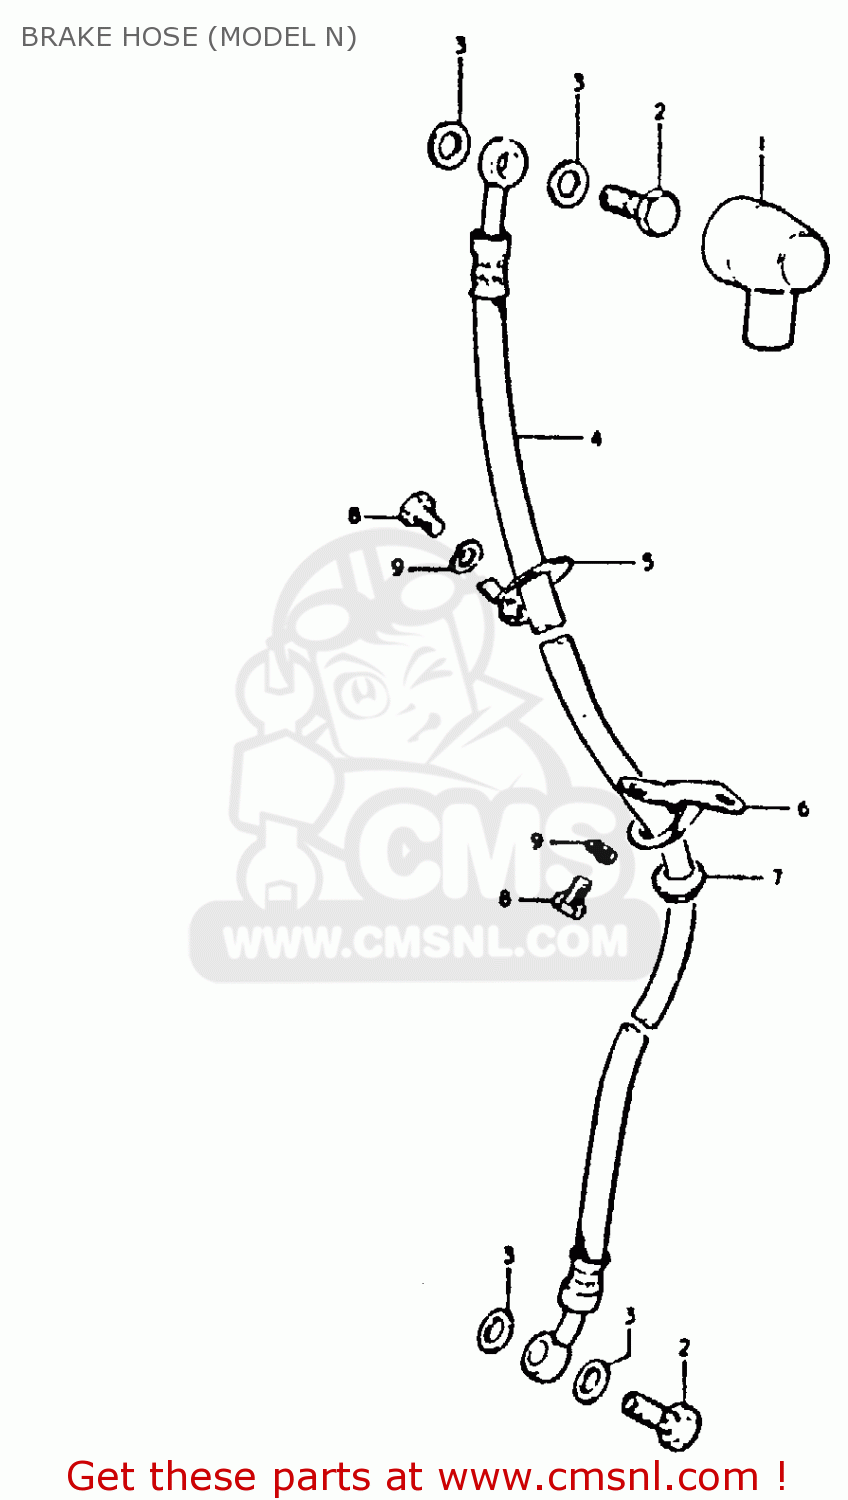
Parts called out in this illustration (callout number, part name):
1	BOOT
2	BOLT UNION
3	WASHER
4	HOSE, BRAKE (FLAT)
5	GUIDE, HOSE NO.1
6	GUIDE,BRAKE HOSE
7	GROMMET,BRAKE HOSE GUIDE
8	BOLT
9	LOCK WASHER
